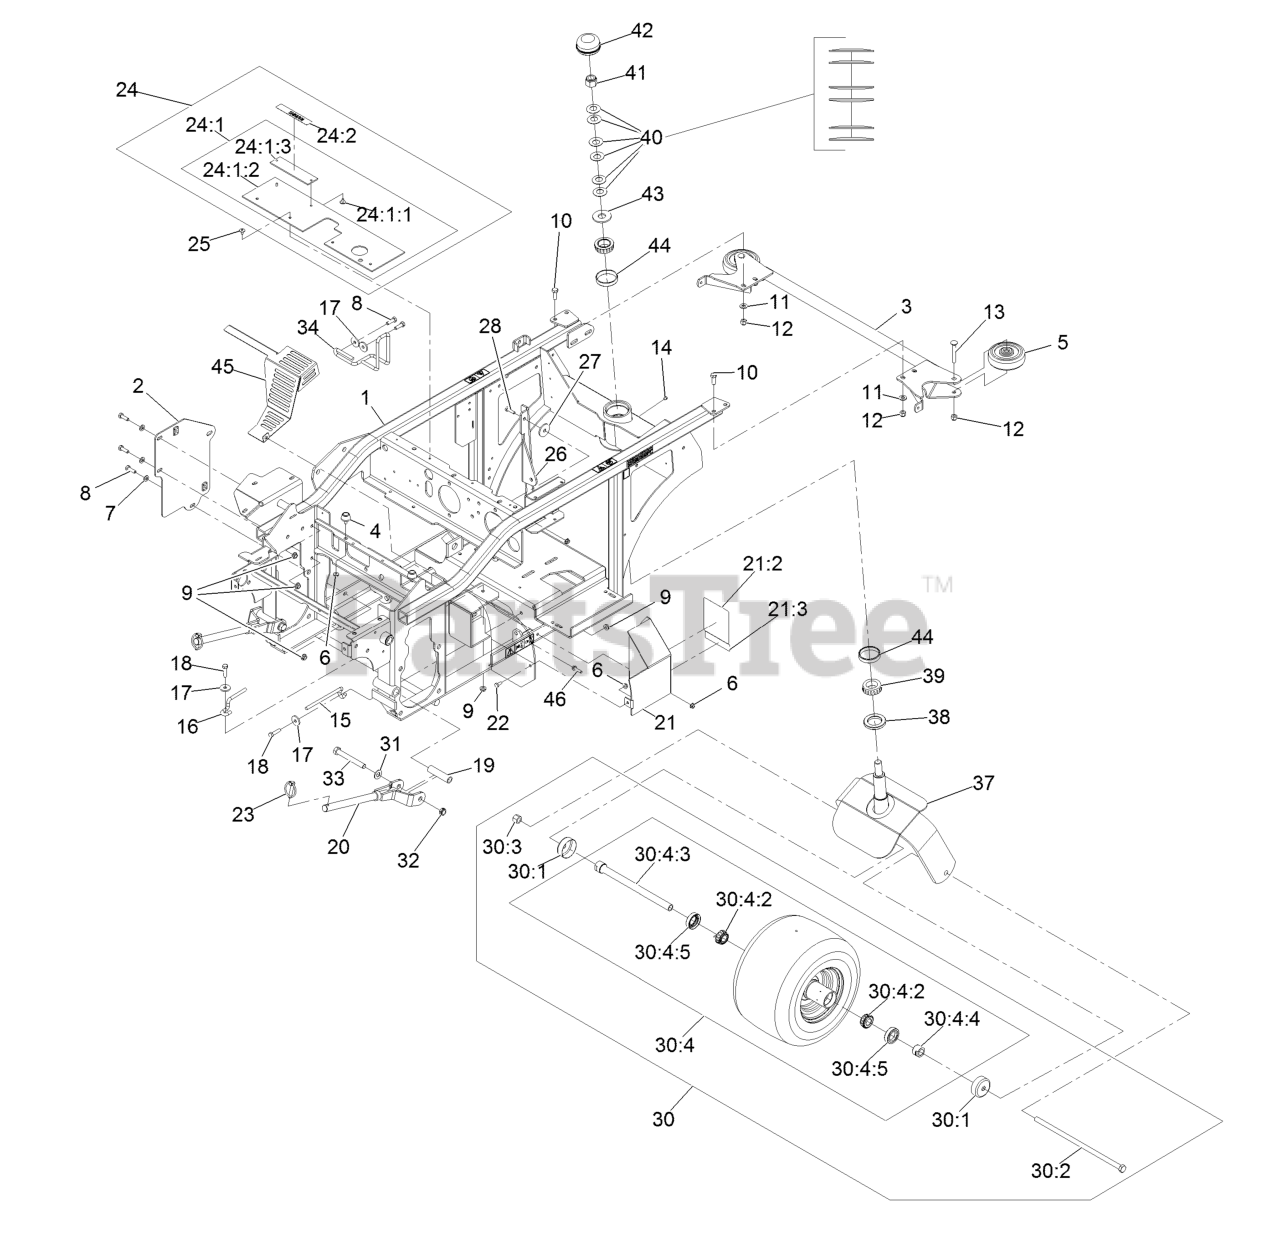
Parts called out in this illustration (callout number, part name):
1	Frame ASM
2	Plate-Support
3	Bumper-Rear
4	Bumper-Rubber
5	Roller-Bumper
6	Nut-Whizlock 1/4-20
7	Washer-5/16 SAE
8	Screw-HH 5/16-18 X 1
9	Nut-Whizlock 5/16-18
10	Screw-HH 3/8-16 X 1
11	Washer-3/8 SAE
12	Nut-Nyloc 3/8-16
13	Bolt-Carriage 3/8-16 X 2 1/2
15	Guide-Belt
16	Guide-Belt
18	Screw-HH 5/16-18 X 1 1/4
19	Spacer-Wheel, Short
21	Drive Shield ASM
21:2	Decal-Belt Routing
21:3	Decal-Warning
22	Screw-HH 1/4-20 X 5/8
23	Pin-Lynch
24	Lift Shield ASM
24:1	Shield-Lift
24:1:1	Rivet 3/16 X 1/4
24:1:2	Flap-Guard
24:1:3	Plate-Decal
24:2	Decal-Warning
25	Rivet 3/16 X 1/4
26	Brace-PTO
28	Screw-HH 1/4-20 X 1
30	Asm, Rear Caster Wheel W/Axle
30:1	Guard-Seal
30:2	Screw-HH 1/2-13 X 13
30:3	Nut-Nyloc 1/2-13
30:4	Asm, Wheel Tire And Brg 13X8.00-6 Sp
30:4:2	Bearing-Cone Tapered Roller
30:4:3	Axle Caster ASM
30:4:4	Spacer-Nut
30:4:5	Seal-Double Lip
31	Washer-1/2 SAE
32	Nut-Nyloc 1/2-13 Thin
33	Screw-HH 1/2-13 X 4
34	Guide-Belt
37	Fork-Rear Caster
38	Seal-Grease
39	Cone-Bearing Taper Roller
40	Washer-Spring Disc
41	Nut-Nyloc 3/4-10
42	Cap-Grease
43	Washer
44	Cup-Bearing Tapered Roller
45	Shield-Heat
46	Screw-HHF
